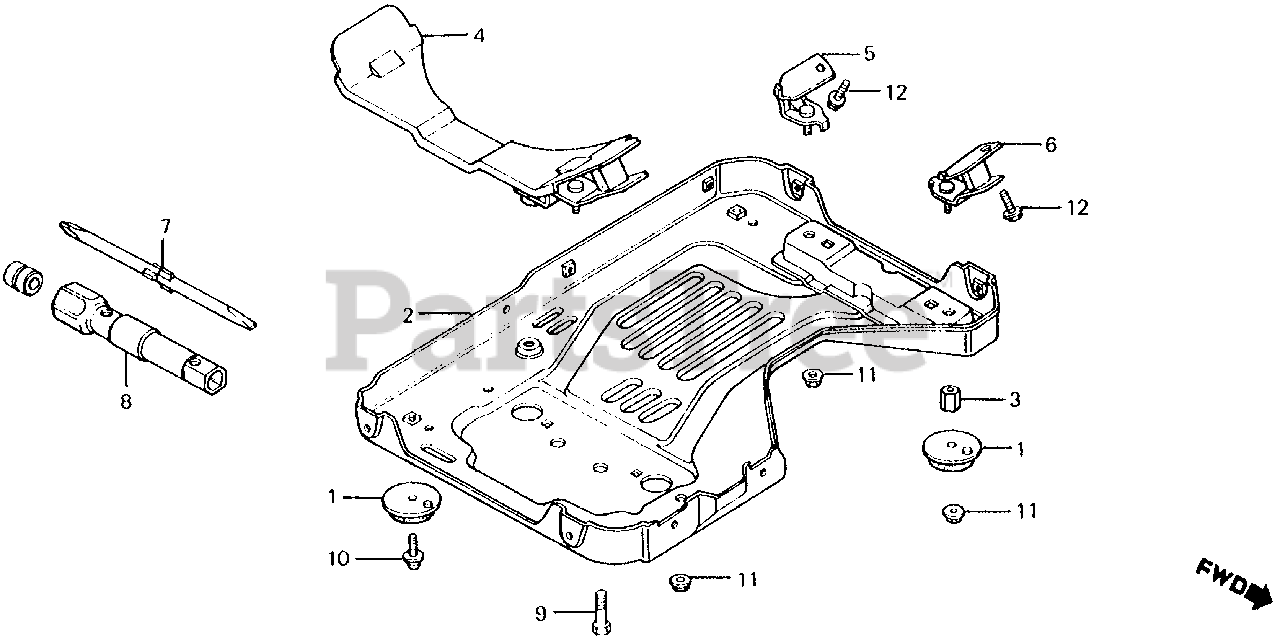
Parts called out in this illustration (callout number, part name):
1	RUBBER (LOWER)
2	COVER (LOWER)
3	STUD (LOWER)
4	RUBBER, ENGINE MOUNTING
5	RUBBER A, SETTING (NOT AVAILABLE)
6	RUBBER B, MOUNT (NOT AVAILABLE)
7	DRIVER (NOT AVAILABLE)
8	WRENCH, BOX (P21X12)
9	BOLT-WASHER (8X16)
10	SCREW-WASHER (6X10)
11	NUT, FLANGE (6MM)
12	BOLT, FLANGE (6X12)
